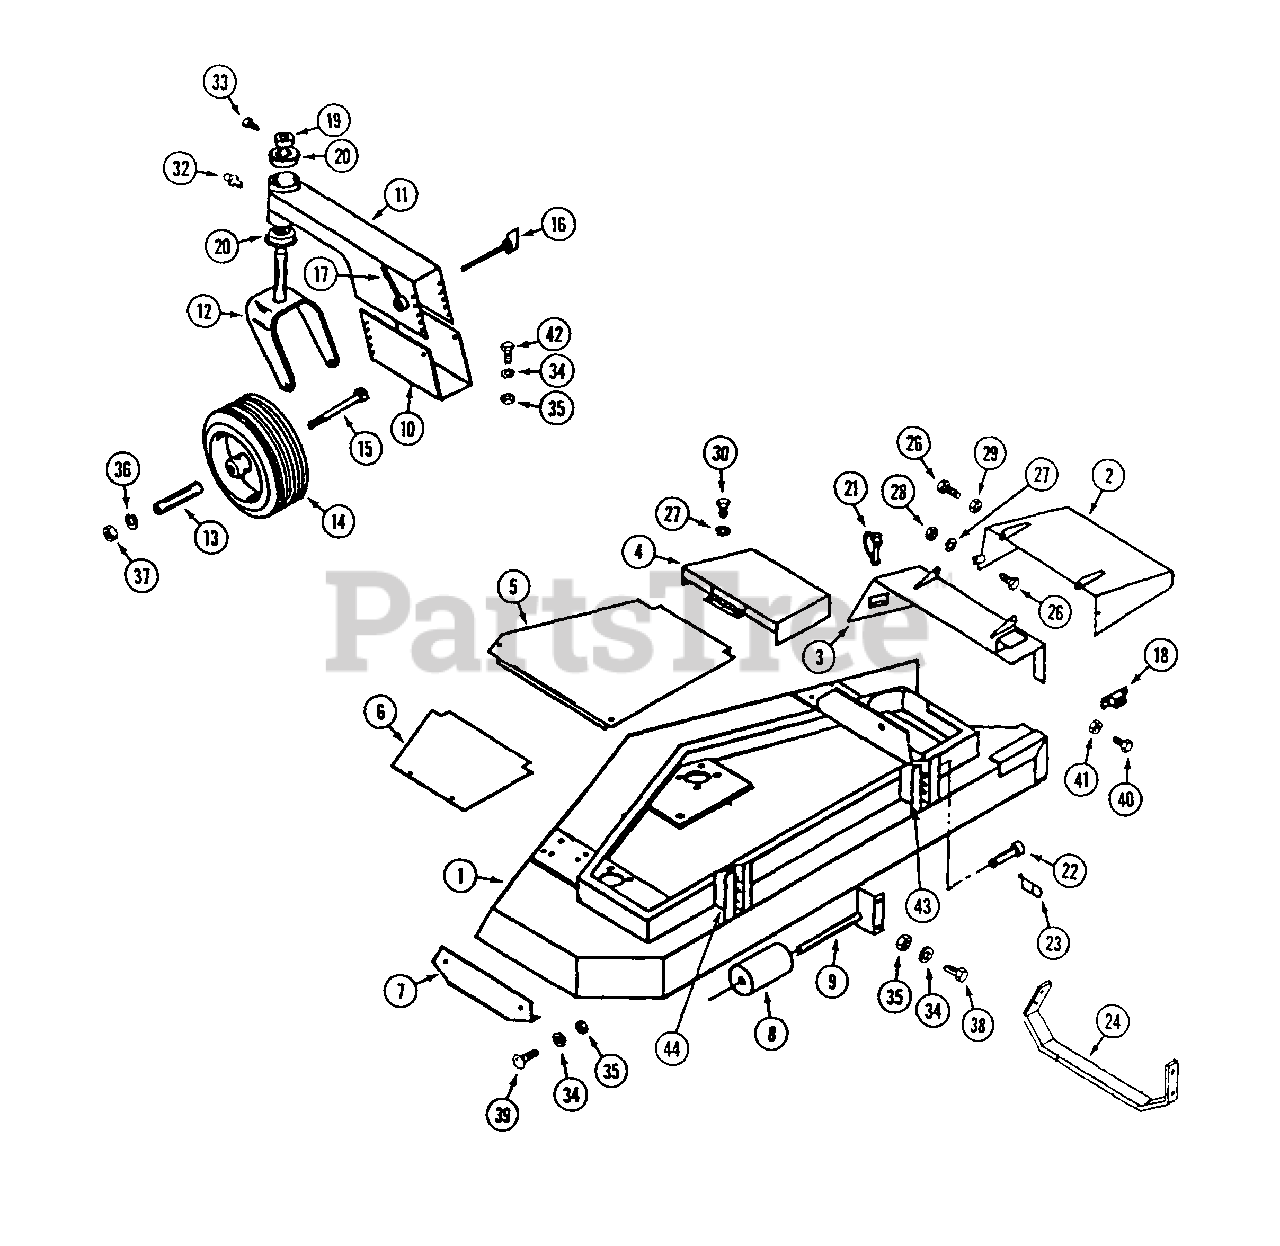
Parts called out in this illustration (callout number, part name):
1	DECK 62"
2	CHUTE - foot guard
3	MOUNT - foot guard
4	COVER - pulley
5	COVER - center
6	COVER - L.H.
8	ROLLER - anti-scalp
9	SHAFT - roller
10	BRACKET - gauge wheel mount
11	MOUNT - gauge wheel
14	WHEEL - gauge
15	BOLT - 1/2" - 13 x 6-1/2"
17	NUT - gauge wheel handle
18	BREAKER - circuit, 10 amp
21	PIN - "fas-tatch"
23	PIN - cotter, hair
24	SHOE - skid R.H.
26	BOLT - 1/4" - 20 x 3/4"
27	LOCKWASHER - 1/4"
28	NUT - 1/4" - 20
29	NUT - 1/4" - 20 lock
30	BOLT - 1/4" - 20 x 1"
32	FITTING - grease
33	SCREW - set 5/16" - 18 x 1/2" square head
34	LOCKWASHER - 5/16"
35	NUT - 5/16" - 18
36	LOCKWASHER - 1/2"
37	NUT - 1/2" - 1 3
38	BOLT - 5/16" - 18 x 3/4"
39	BOLT - 5/16" - 18 x 3/4" carriage
40	SCREW - #10 - 32 x 1/2"
41	NUT - #10 - 32
42	BOLT - 5/16" - 18 x 1" carriage
43	BRACKET - height adjust R.H.
44	BRACKET - height adjust L.H.
